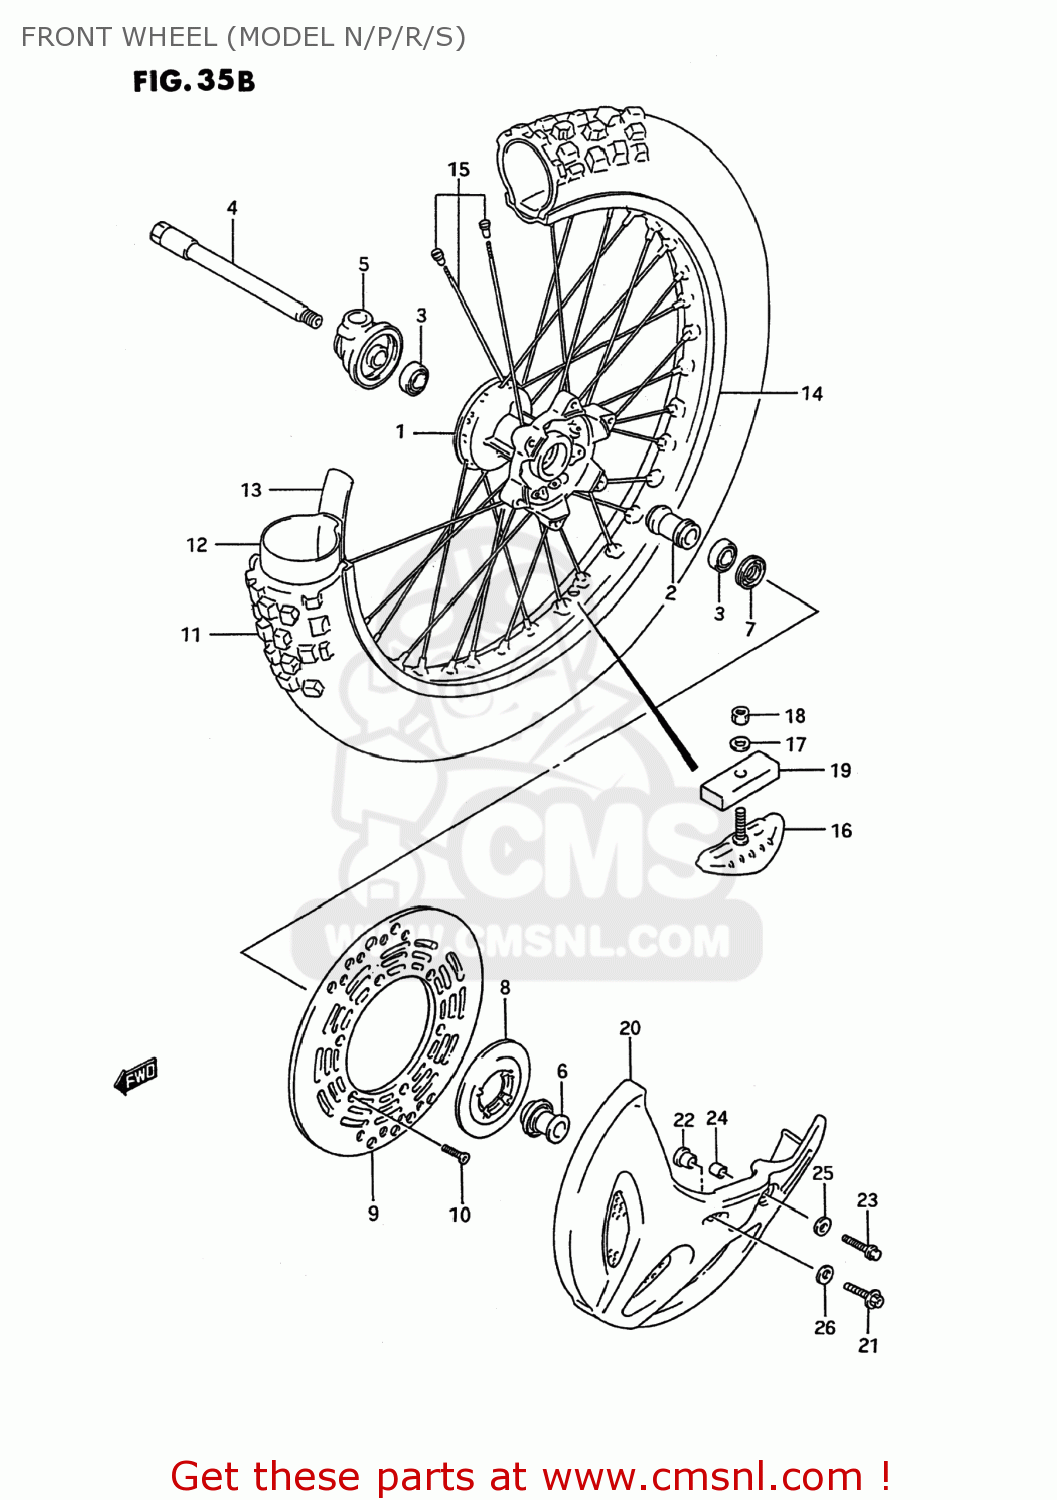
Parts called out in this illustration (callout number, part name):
1	HUB,FRONT WHEEL
2	SPACER,FR HUB BEARING
3	BEARING
4	AXLE,FR
5	BOX ASSY,SPEEDOMETER GEAR
6	SPACER,FR AXLE,L
7	SEAL,OIL(23X35X6)
8	CAP,FR HUB,L
9	DISC,FR BRAKE
10	SCREW
11	TIRE,FRONT 80/100-21
12	TUBE
13	PROTECTOR,WHEEL INNER
14	RIM,FRONT WHEEL (1.60X2
15	SPOKE SET,FRONT
16	STOPPER,BEAD
17	WASHER
18	NUT
19	CUSHION,BEAD STOPPER
20	COVER,FR BRAKE DISC
21	BOLT
22	WASHER (8.5X16X1.6)
23	BOLT
24	SPACER(6.1X8X14.5)
25	WASHER(6.5X18X1)
26	WASHER(8.5X18X1)
